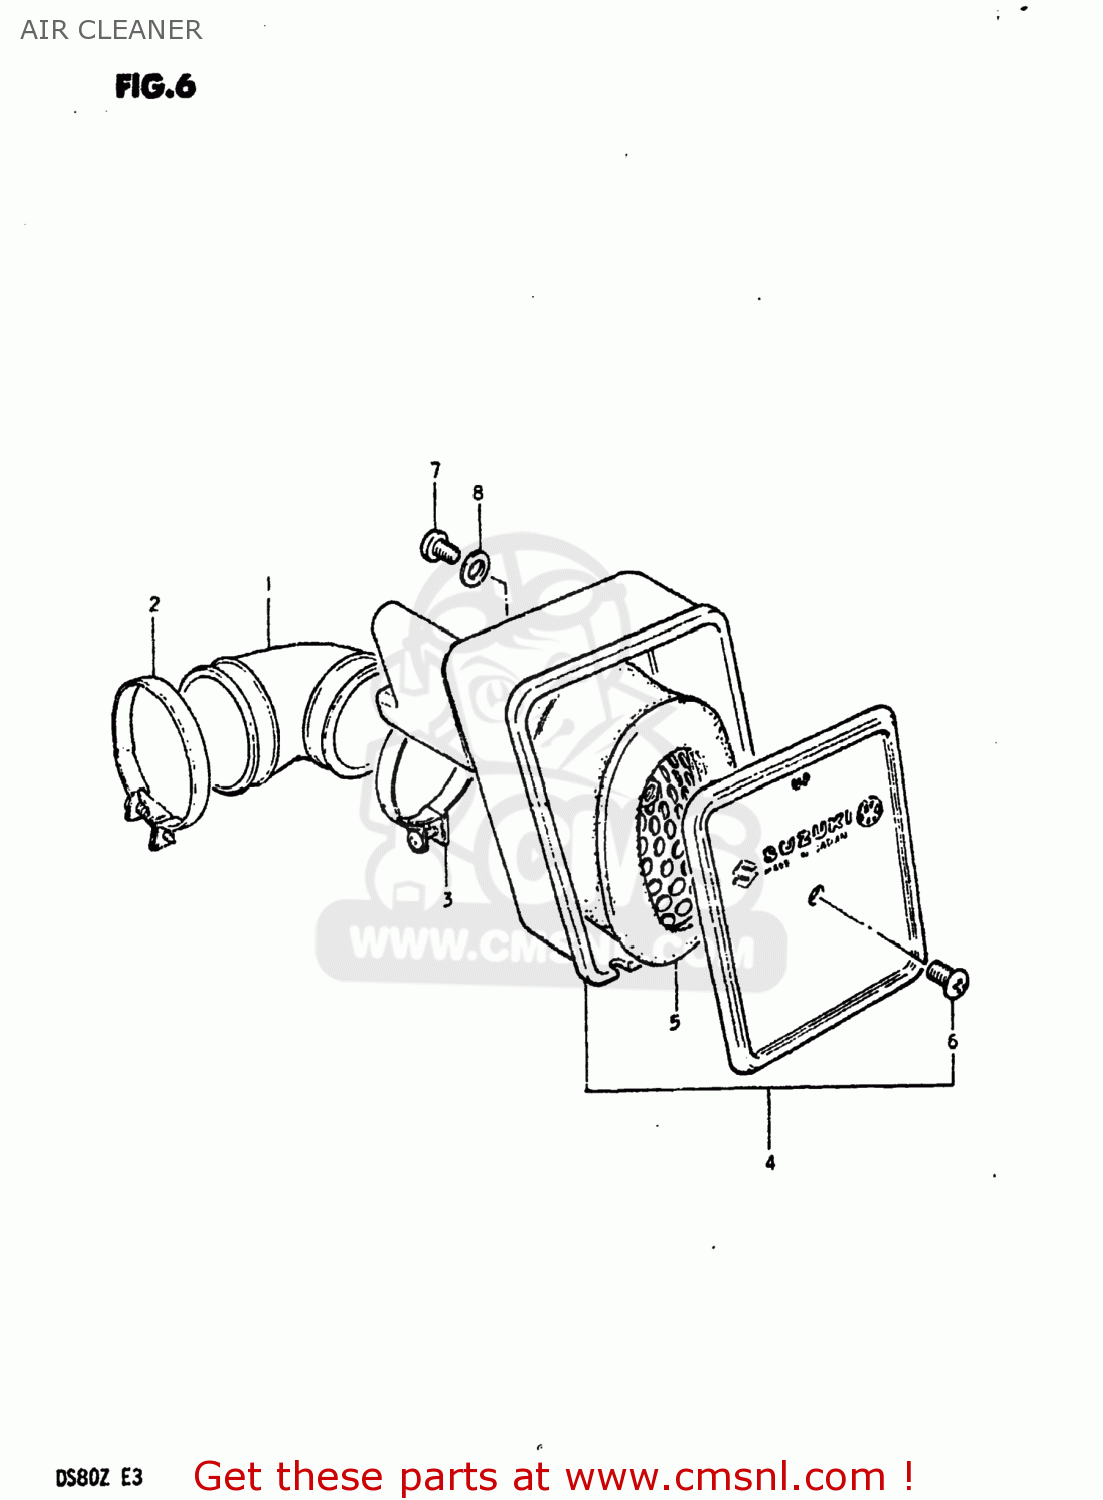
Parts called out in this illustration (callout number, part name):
1	HOSE,CARBURETOR AIR INLET
2	CLAMP
3	CLAMP
4	CLEANER ASSY,AIR
5	FILTER
6	SCREW
7	SCREW
8	WASHER
